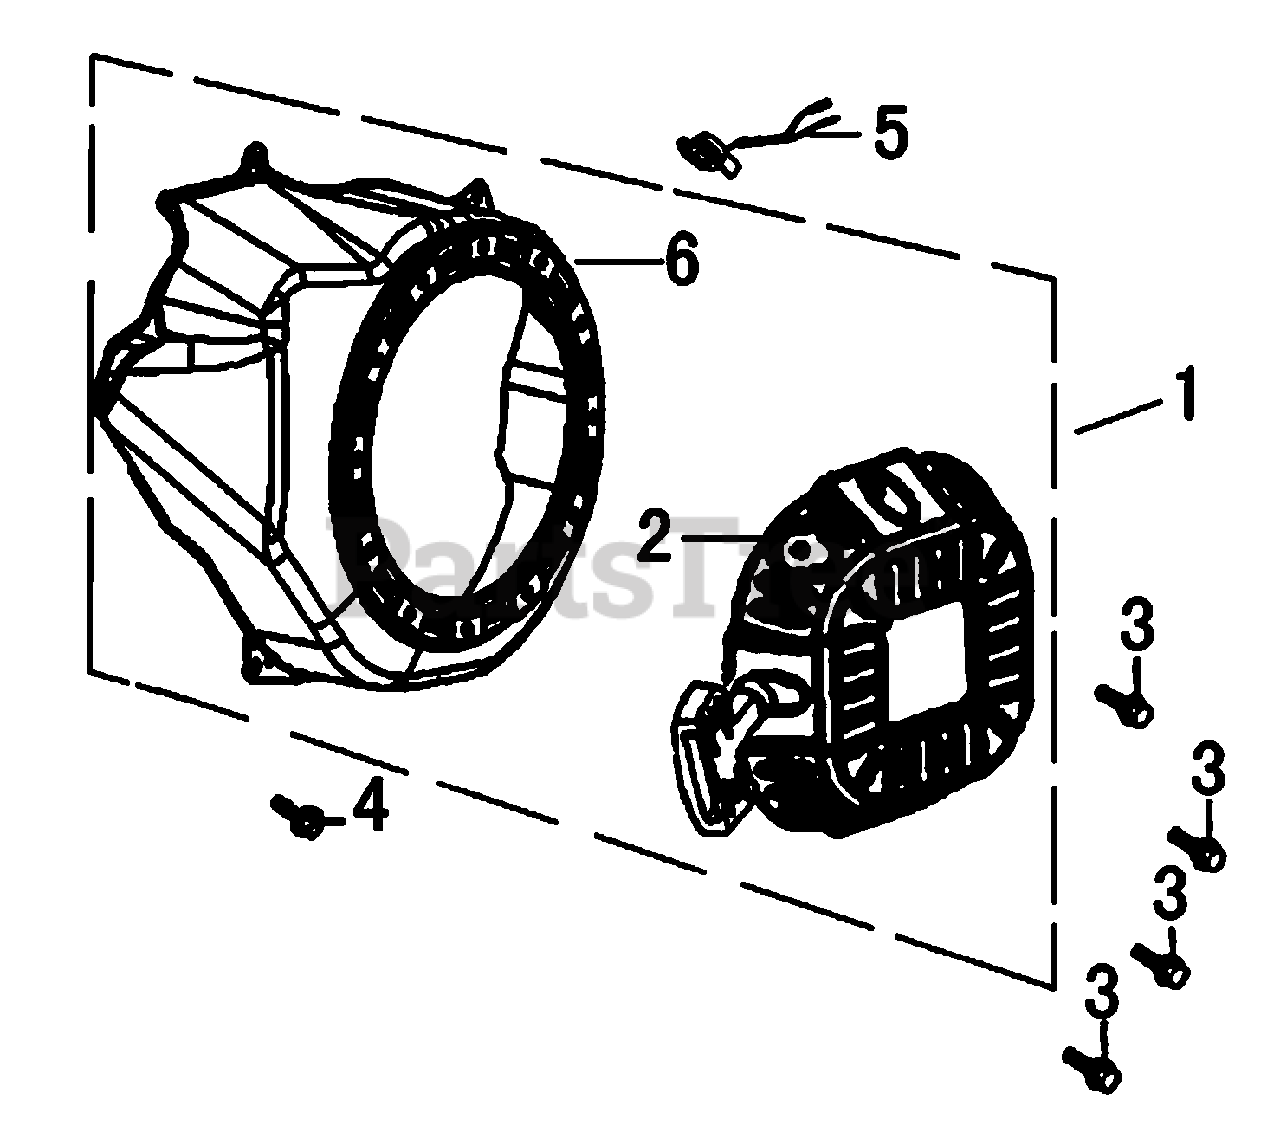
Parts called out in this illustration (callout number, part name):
1	RECOIL STARTER W/HSNG
2	RECOIL STARTER ASSY.
3	BOLT, FLANGE 6X8
4	BOLT, FLANGE 6X10
5	SWITCH ASSY., ENGINE STOP
6	HOUSING, BLOWER
